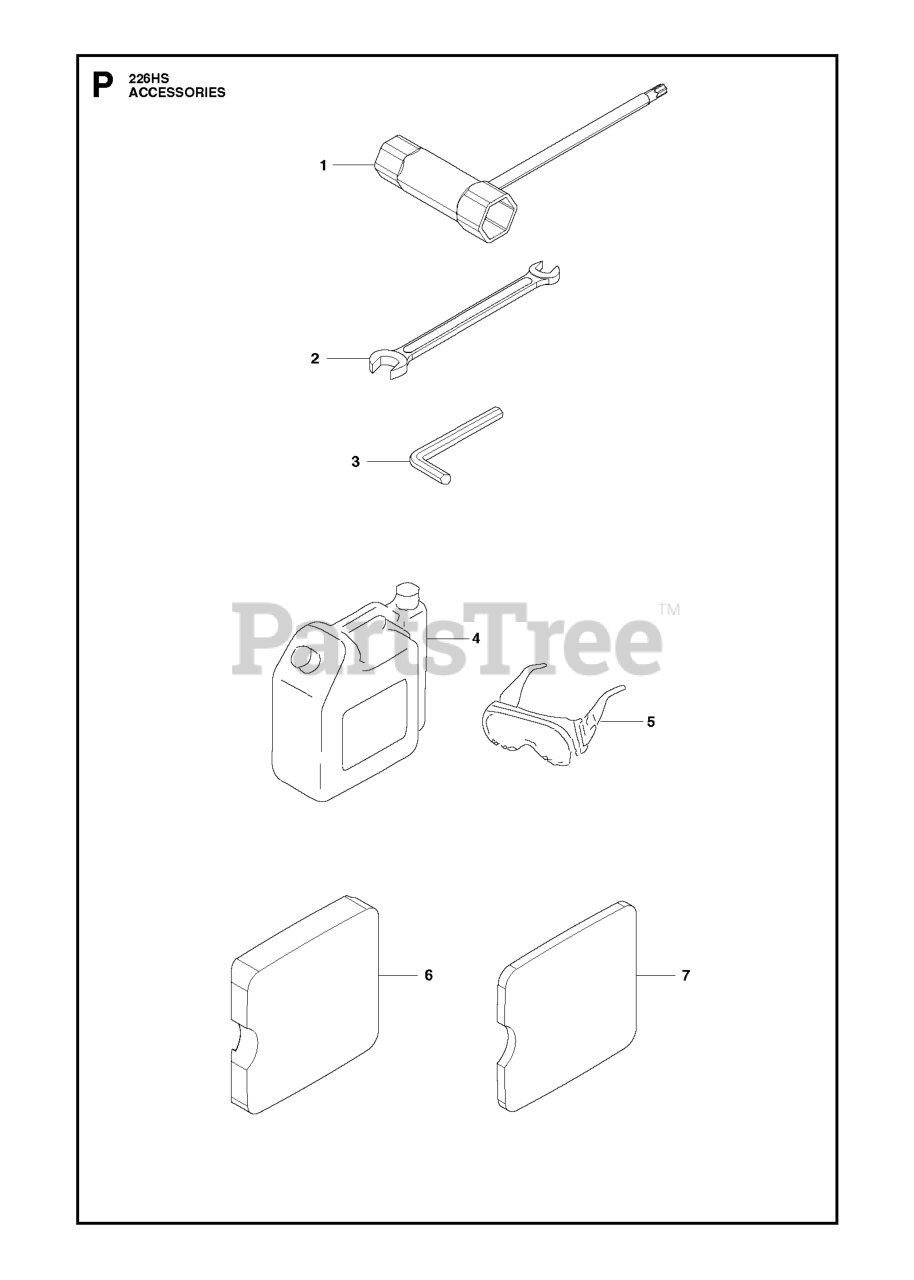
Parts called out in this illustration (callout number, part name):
2	WRENCH SPANNER
3	WRENCH
4	TANK
5	GOGGLE
6	FILTER FOAM
7	FILTER
